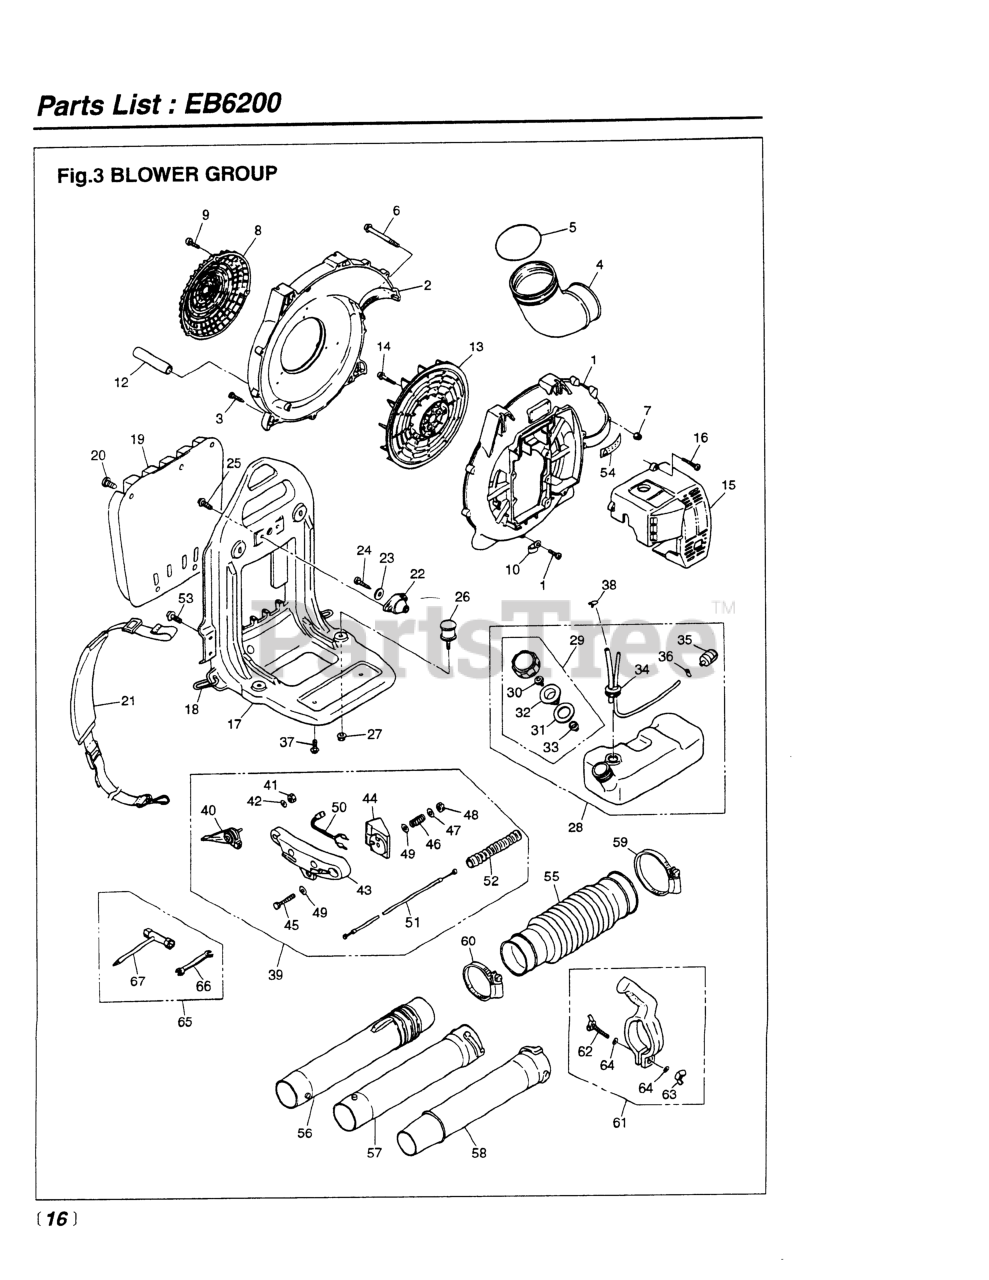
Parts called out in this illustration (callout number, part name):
2	COVER, VOLUTE
3	SCREW, M5 X 25
5	O-RING
6	SCREW, M5 X 70
7	NUT (B)
8	COVER, INLET
9	SCREW, M5 X 25
10	CLAMP
12	TUBE (RPLS. 07270-01507)
13	FAN
14	BOLT (RPLS 3405-12211)
15	COVER, ENGINE (RPLS -31611)
16	SCREW, M5 X 25
18	RING (USE -21121)
19	PAD (RPLS -21310)
20	CLIP (RPLS 3490-21320)
21	BAND ASSY (RPLS 2750- )
22	DAMPER, UPPER
23	WASHER
24	SCREW
25	BOLT, M5 X 16 (USE -32541)
26	DAMPER, LOWER
27	NUT, M6
30	VALVE (NLA WHEN OUT)
31	PACKING
32	HOLDER (USE -85300)
33	HOLDER, CAP
34	PIPE COMP.(RPLS 2756-85300)
35	FILTER ASSY
36	CLIP (REPLACES 2841-31280)
37	SCREW, M5 x 12
38	CLIP
39	LEVER SET
40	LEVER, THROTTLE
41	NUT (B)
42	WASHER, M5x.8(RPLS 01624-20508
43	ARM (RPLS -25211)
44	BRACKET
45	BOLT
46	SPRING
47	WASHER
48	NUT, M6 X 5
49	WASHER, FLAT
50	SWITCH, STOP
51	CABLE, THROTTLE
52	TUBE (USE 5548-73310)
53	BOLT, M5 X 16 (USE -32541)
54	LABEL, CAUTION
56	JOINT, SWIVEL (USE 51201)
58	PIPE, END
59	CLAMP (RPLS 3490- )
60	CLAMP (RPLS 3050-13230)
61	GRIP ASSEMBLY (USE 2750-51501)
62	BOLT, WING
63	NUT, WING
64	WASHER
65	TOOL SET
66	SPANNER, 8 X 10 (RPLS 2540- )
67	WRENCH, SOCKET
